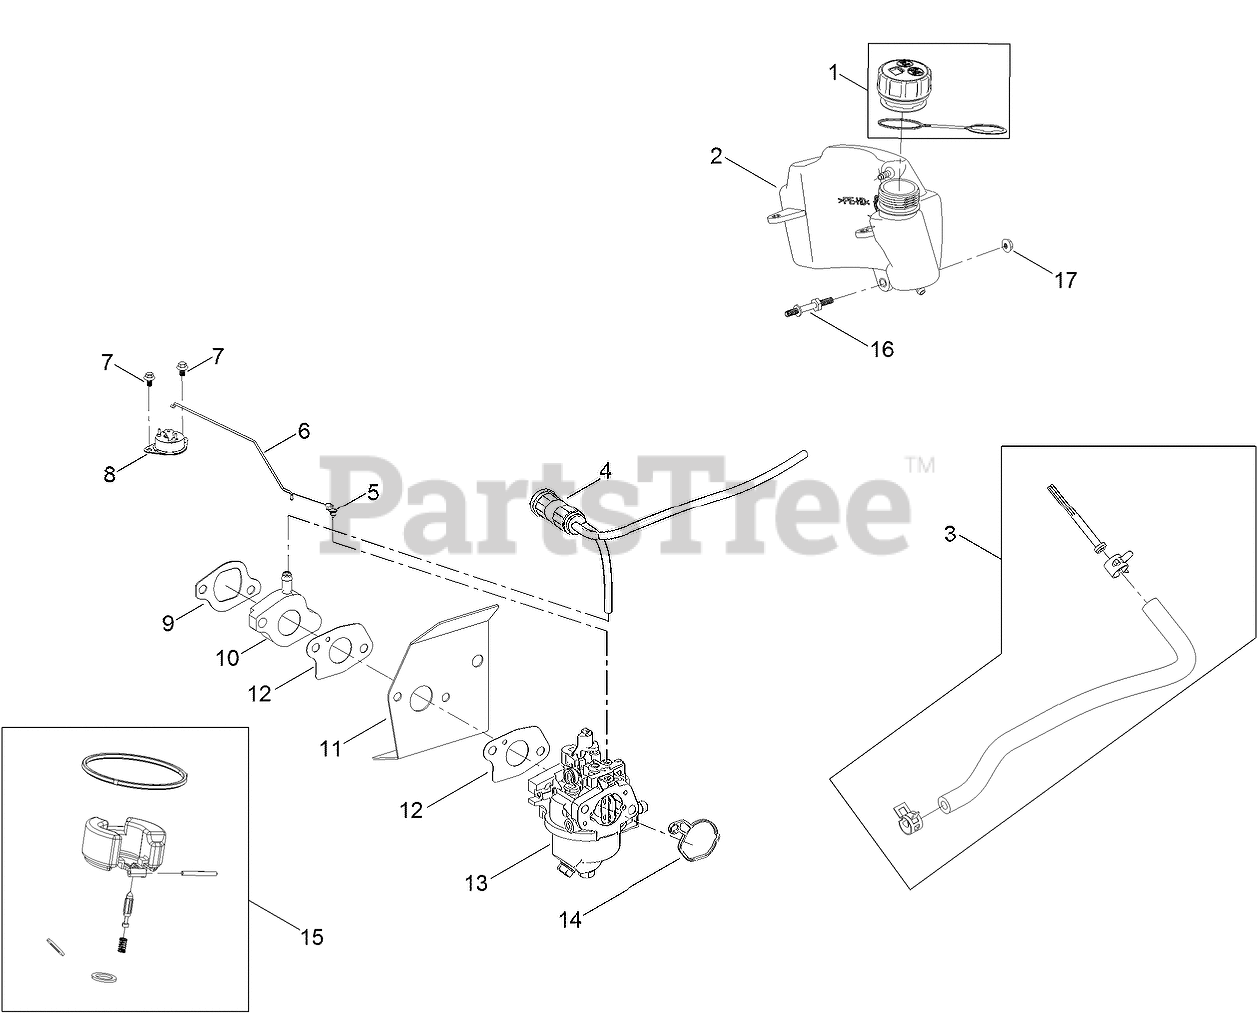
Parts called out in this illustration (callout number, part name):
1	CAP-FUEL, SEALED
2	TANK-FUEL
3	FUEL LINE KIT
4	CANISTER-CARBON, 19 CC
5	LOCK-THROTTLE
6	LINKAGE-CHOKE, THERMAL
7	SCREW-HWHTF
8	CONTROL-THERMAL
9	GASKET-INTAKE
10	SPACER-CARBURETOR
11	INSULATOR-CARBURETOR
12	GASKET-CARBURETOR
13	CARBURETOR
14	GASKET-CARBURETOR
15	INTERNAL CARB SERVICE KIT
16	BOLT-STUD
17	NUT-FLANGE
